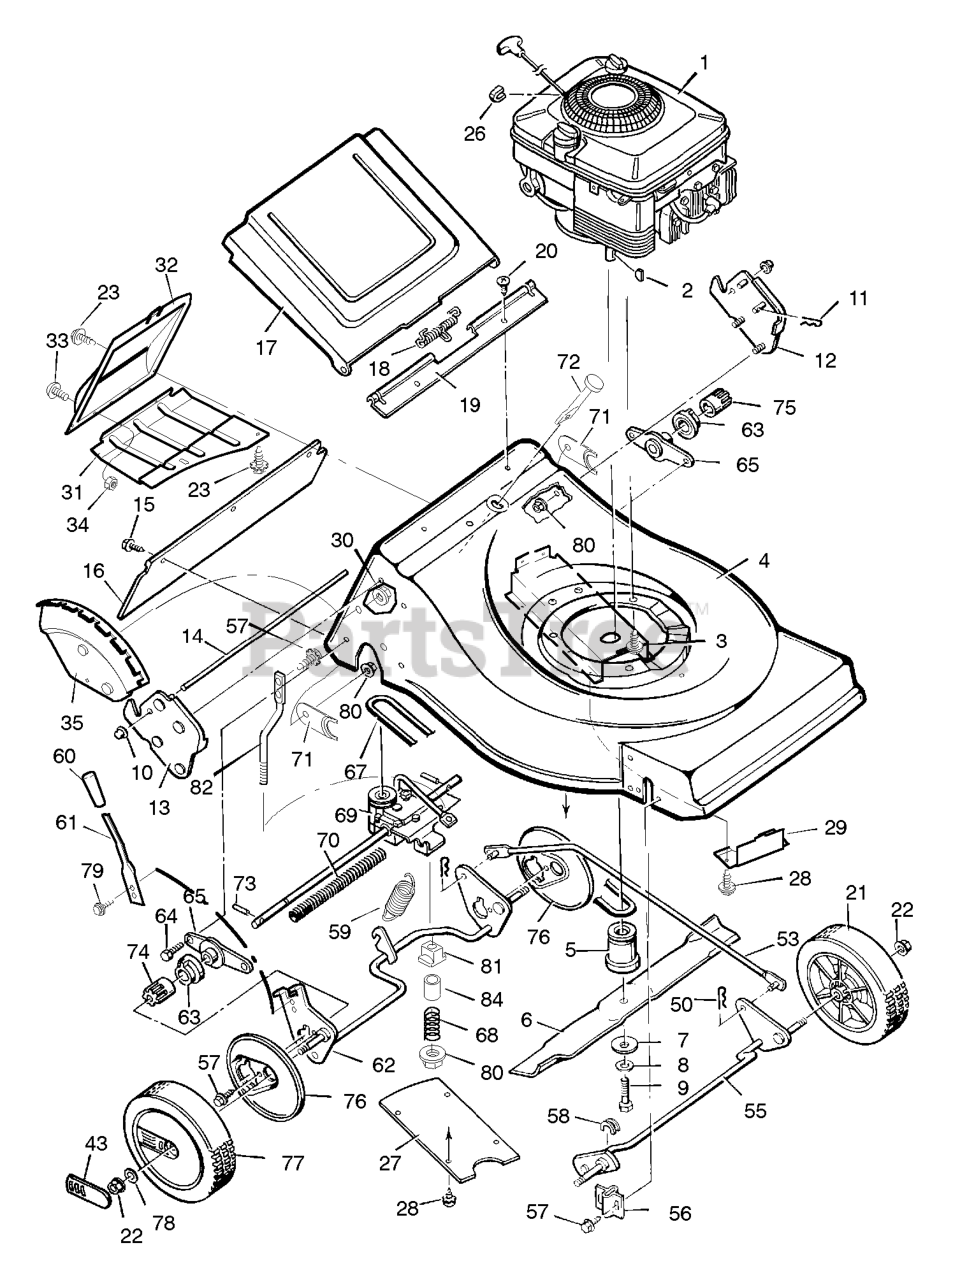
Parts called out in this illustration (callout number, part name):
1	Engine *
2	Key, Woodruff
3	Bolt, Engine
4	Housing
5	Adapter, Blade
7	Washer, Belleville
10	Push On Cap
11	Pin, Hair
12	Handle Bracket, Left
13	Handle Bracket, Right
14	Rod, Door Pivot
16	Deflector, Rear
17	Door, Rear
18	Spring, Torsion
19	Spacer, Door
21	WHEEL & TIRE ASSEMBLY, White, 8"
22	Nut
26	Stop, Rope
27	Cover, Belt
29	Cover, Front Belt
30	Nut, Hex Flange
31	Cover, Lower
32	Cover, Rear
33	Screw
35	Bracket, Index
43	Hub Cap
50	Pin, Hair
53	Link, Lifter
55	Crossbar, Front
56	Clip, Retainer
58	Bushing
59	Spring, Extension
60	Grip, Height Adjuster
61	Lever, Height Adjuster
62	Crossbar, Rear
63	Bearing, Lifter
64	Bolt, Hex
65	Support, Axle
67	Belt, Drive
68	Spring
69	Transmission TIM .50
70	Shield, Axle
71	Retainer, Bearing
72	Support, Lifter Spring
73	Pin, Drive
74	Pinion, Right
75	Pinion, Left
76	Cover, Dust
77	Wheel, Drive - White
78	Washer, Thrust
80	Locknut
81	Bushing
82	Support, Spring
